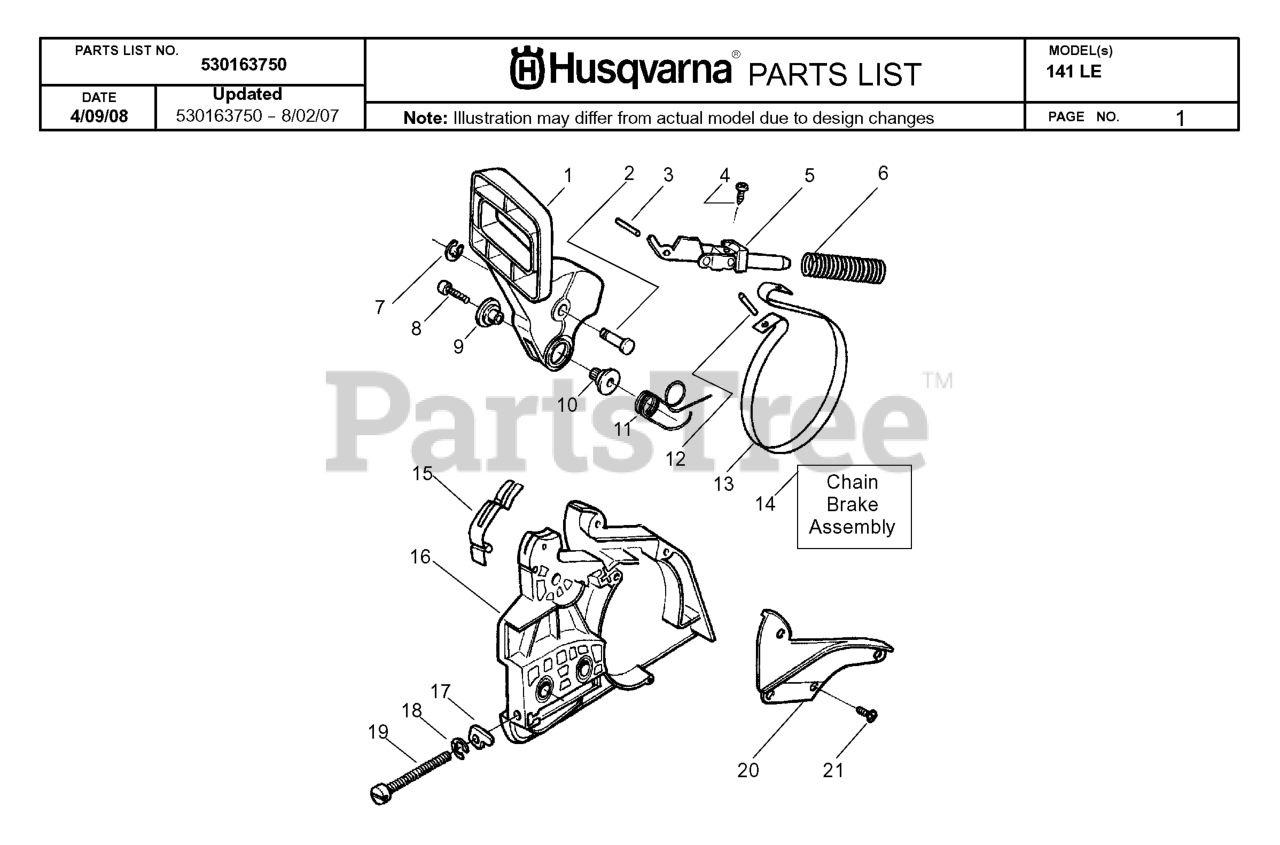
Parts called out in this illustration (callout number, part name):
4	SCREW
5	FRONT LINK ASSY
6	%COMPRESSION SPRING
9	JOURNAL, RIGHT
10	SHAFT PIVOT
11	SPRING,BRK HDL 36/41
13	BRAKE BAND
14	CHAIN BRAKE ASM.
15	SPRING-POSITION
16	CLUTCH COVER
17	ADJUST PIN,BAR 36/41
19	BAR ADJUSTING SCREW
20	CHAIN BRAKE COVER
21	SCREW
